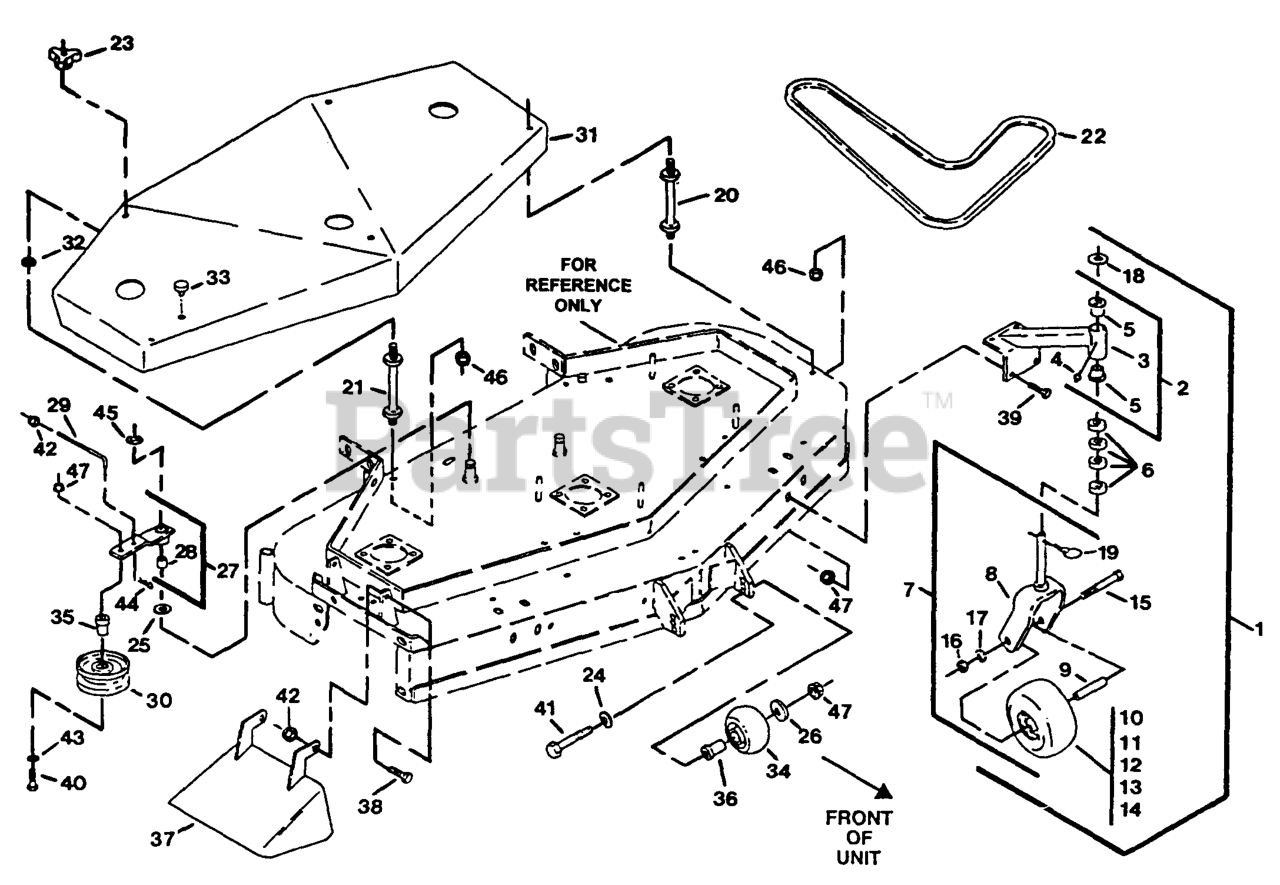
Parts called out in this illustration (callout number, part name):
1	CASTER/MOUNT ASM
2	SUPPORT ASM
5	BEARING-FLANGED
6	SPACER-CASTER
13	BEARING
14	BUSHING
18	WASHER-FLAT
20	STUD-SHIELD, BELT (SHORT)
21	STUD-SHIELD, BELT (LONG)
23	KNOB-3 PRONG
25	WASHER-SPINDLE
27	ARM WLDMNT W/BUSHING
28	BEARING,POWDERED METAL
29	LINKAGE
30	IDLER,PULLEY
31	BELT SHIELD ASSY 52METR
34	ROLLER-SCALP, ANTI
35	BUSHING-IDLER
36	BUSHING-ROLLER
37	WLD,CHUTE DISCHARGE
44	PIN-COTTER
